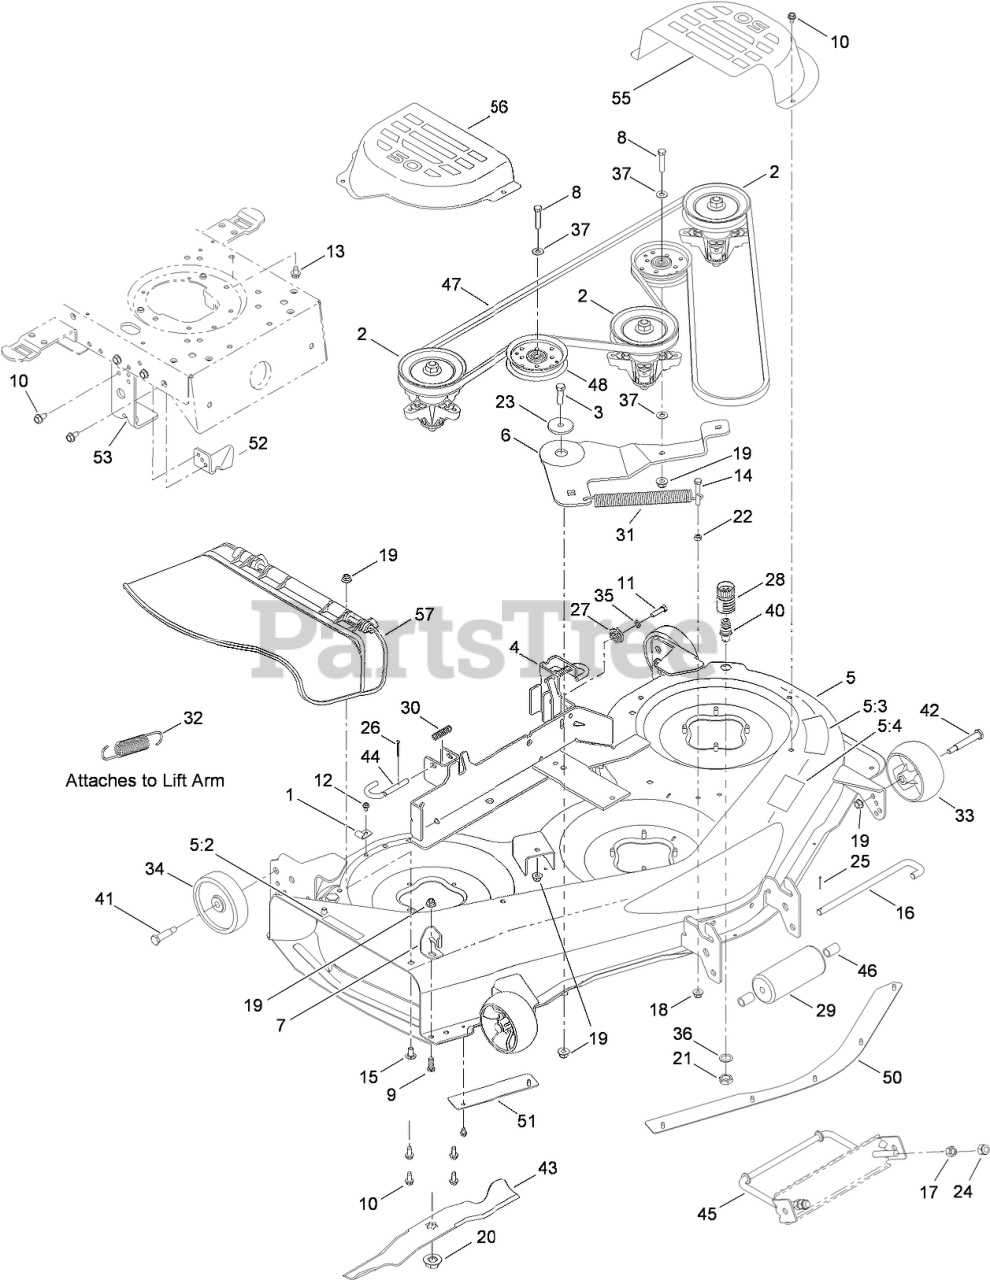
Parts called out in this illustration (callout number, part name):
1	BRACKET-RETAIN, HOOK
2	SPINDLE ASM
3	SCREW-HH
4	LH HANGER BRACKET ASM
5	DECK WITH DECALS
5:2	DECAL-DECK
5:3	DECAL-BELT ROUTING, DECK
5:4	DECAL-CHUTE
6	BRACKET-IDLER
7	STOP-CHUTE
8	SCREW-HH
9	SCREW-HH
10	SCREW-TAP
11	SCREW-HH
12	SCREW-HWHTF
13	SCREW-TAP
14	SCREW-HH
15	BOLT-CARR
16	PIN-ROLLER
17	NUT-HEX
18	NUT-LOCK, FLANGE
19	NUT-LOCK, FLANGE
20	NUT-LOCK, FLANGE
21	NUT-HEX
22	NUT-HEX
23	SPACER-SHOULDER
24	NUT-LOCK, HEX (NYLON)
25	PIN-COTTER
26	PIN-COTTER
27	GEAR-ADJUSTMENT, DECK
28	ADAPTER-NOZZLE, WATER
29	ROLLER-FRONT
30	SPRING-COMPRESSION
31	SPRING-EXTENSION
32	SPRING-LIFT, ASSIST
33	WHEEL-DECK, FRONT
34	WHEEL-DECK, REAR
35	WASHER-LOCK
36	WASHER-LOCK
37	WASHER-FLAT
40	NOZZLE-WATER, DECK
41	BOLT-SHOULDER
42	BOLT-SHOULDER
43	BLADE-STAR, 17.90
44	PIN-HANDLE, DECK RELEASE
45	ROD-FRONT, ADJUST
46	SPACER
47	BELT-V, SECTION A
48	PULLEY-IDLER, 4.25 INCH
50	SKIRT-CENTER
51	SKIRT-RH
52	BRACKET-CLUTCH
53	BRACKET-DECK, UP STOP
55	COVER-BELT, LH
56	COVER-BELT, RH
57	CHUTE DEFLECTOR ASM
